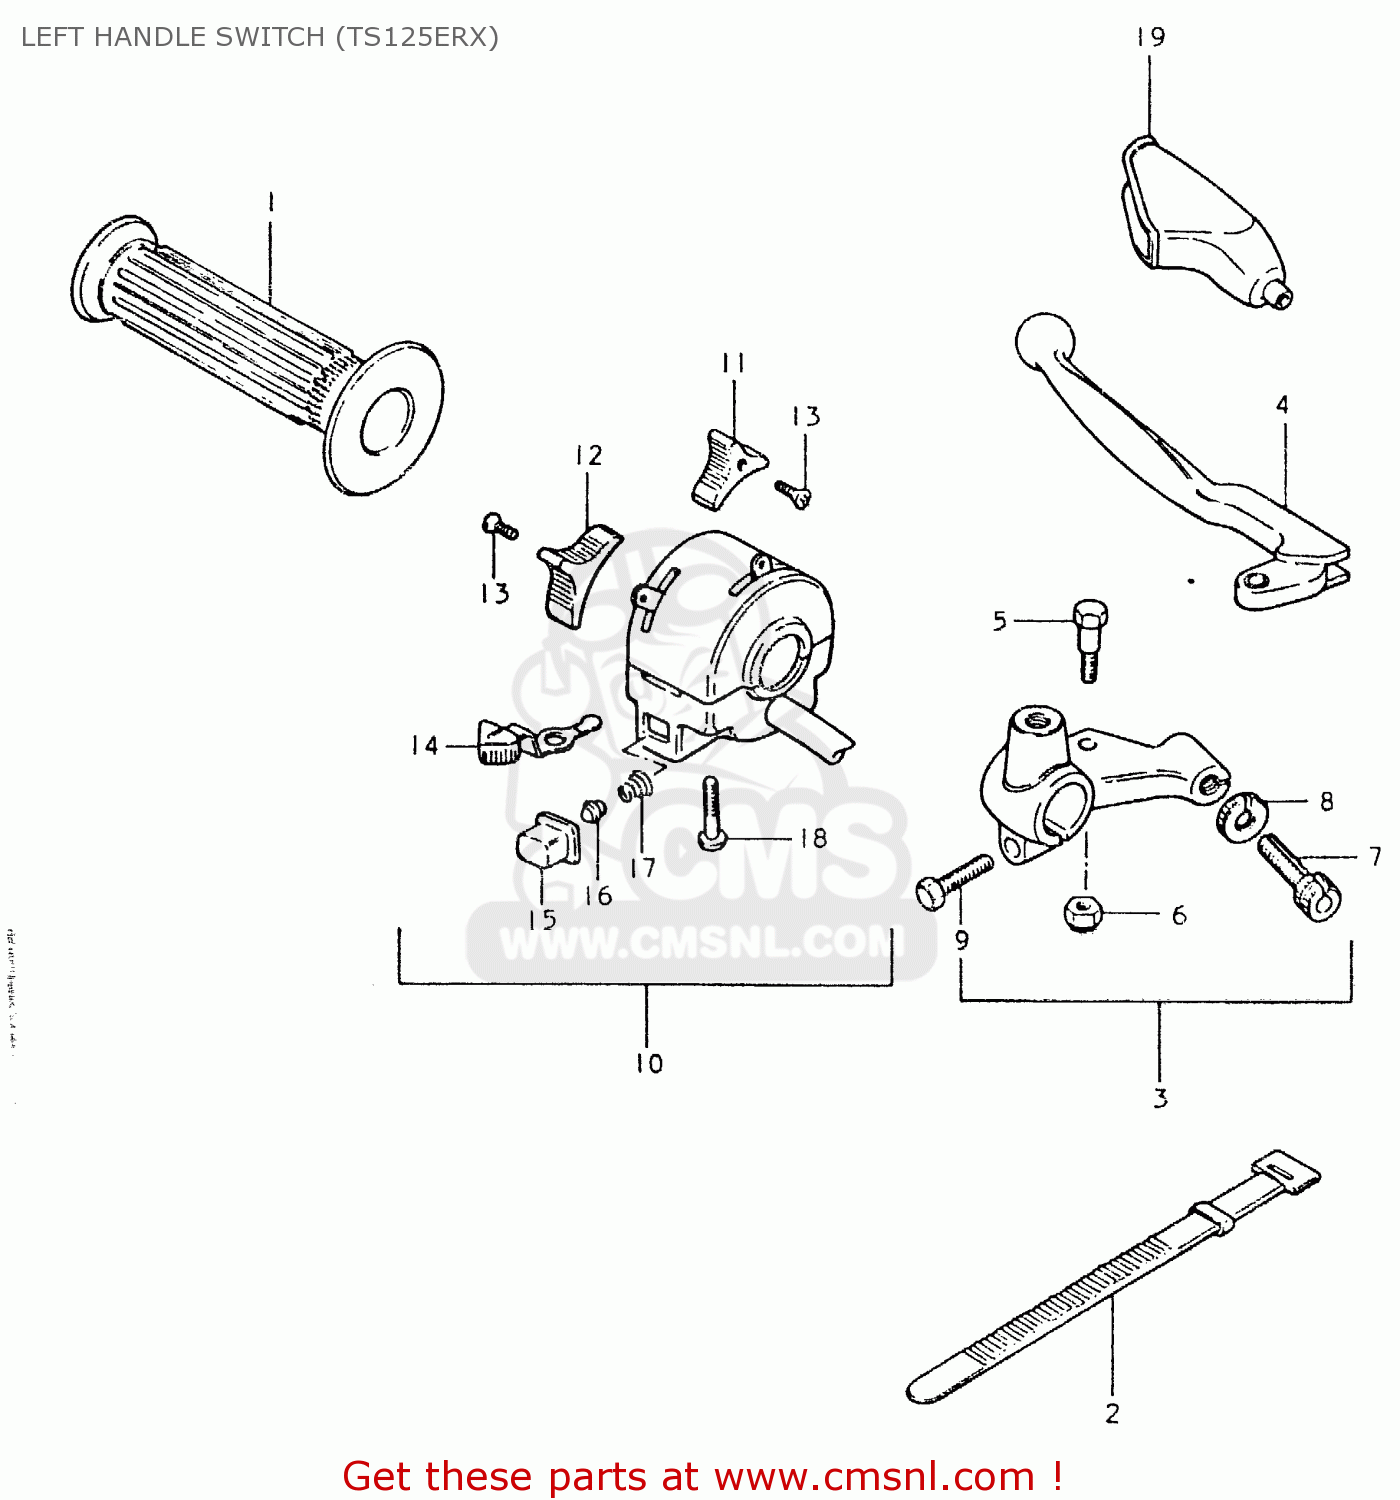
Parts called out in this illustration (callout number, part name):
1	GRIP,L
2	CLAMP(L:120)
3	LEVER ASSY,CLUTCH
4	LEVER,CLUTCH
5	BOLT,LEVER
6	NUT 6MM
7	ADJUSTER,CABLE
8	NUT,CABLE ADJUSTER
9	BOLT
10	SWITCH ASSY,HANDLE,L
11	KNOB,LIGHTING SWITCH
12	KNOB,DIMMER SWITCH
13	SCREW
14	KNOB,TURNSIGNAL
15	BUTTON,HORN
16	CONTACT
17	SPRING
18	SCREW
19	COVER,CLUTCH LEVER
